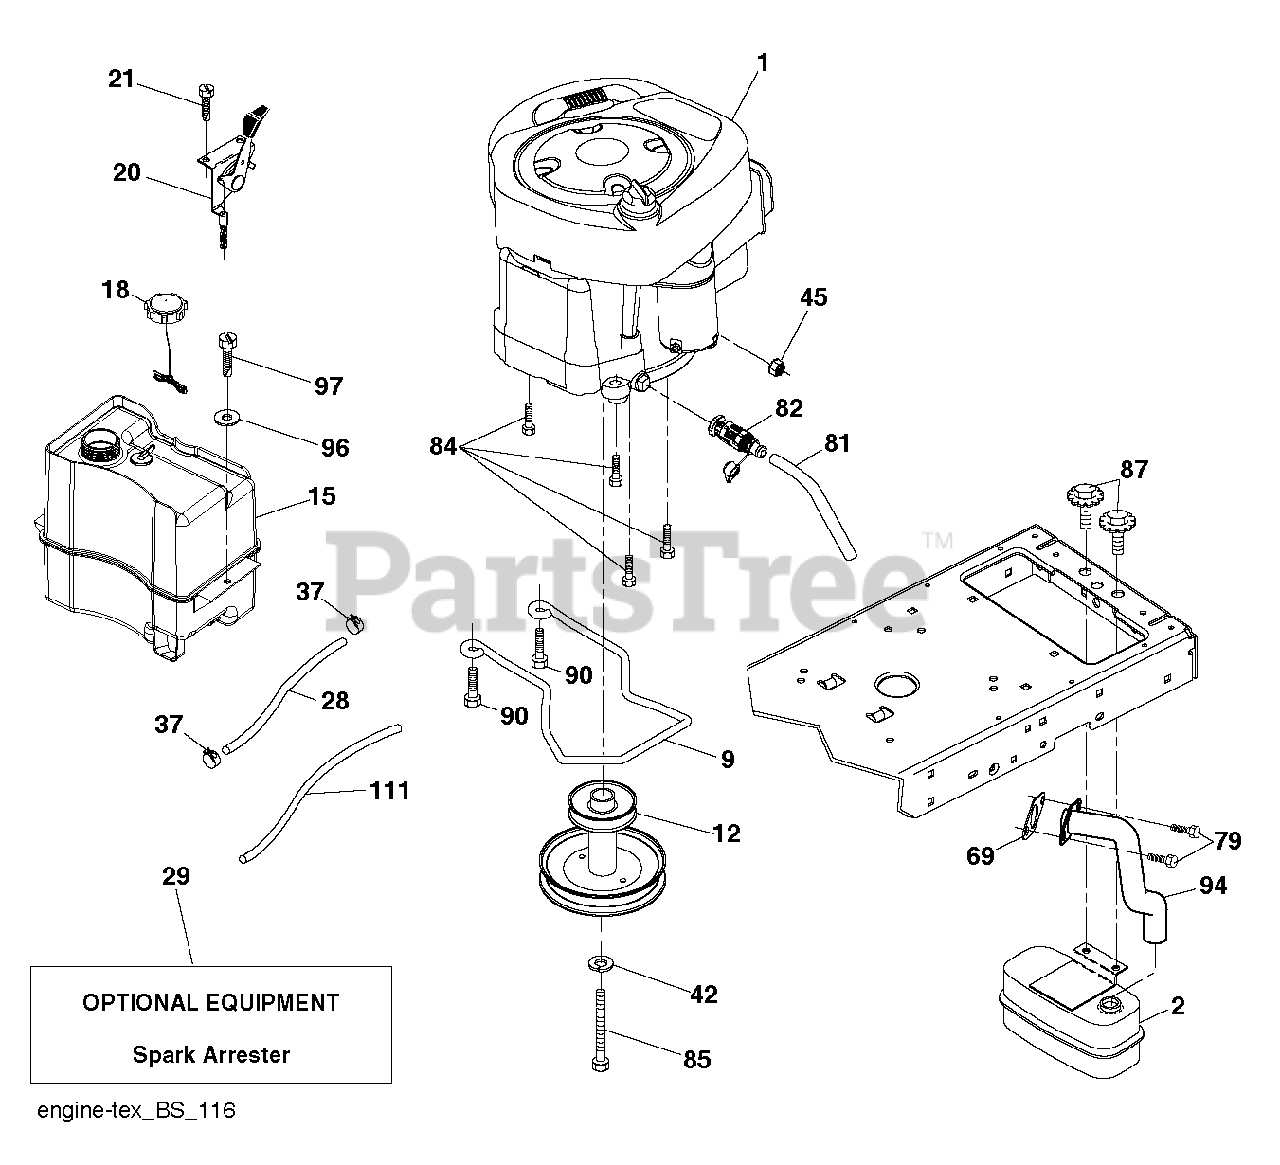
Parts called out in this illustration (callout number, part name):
2	MUFFLER.ASM.SNGL.XTNDED.DFLCTR
9	KEEPER.BELT.ENG.4.25"2.BLT.431
12	ENGINE.PULLEY
15	Front Tank Assembly, 2.5 Gallon
18	CAP.FUEL.2 WAY VENT
20	CONTROL.TH/CK.C.
21	SCREW.#10 X 0.750.BOS
28	LINE.FUEL.20"FRONT.EMI
29	KIT.SPARK ARRESTOR 794945 B&S
37	HOSE CLAMP
42	WASHER 7/16 LOCK
45	NUT
69	REPL BY 532 27 22-93
79	SCREW.SOCKET HD.5/16-1
81	TUBE, DRAIN OIL ASM.
82	VALUE.OIL.DRAIN
84	SCREW.3/8-16
85	BOLT.HEX.7/16-20X4.GR5.1.5BLUE
87	BOLT, 5/16-18 X 1 3/4
90	SCREW 3/8-16X1
94	EXHAUST.TUBE.B&S.28/31
97	SCREW HEXWSHR 1/4-20X3/4
111	RP PURGE LINE
